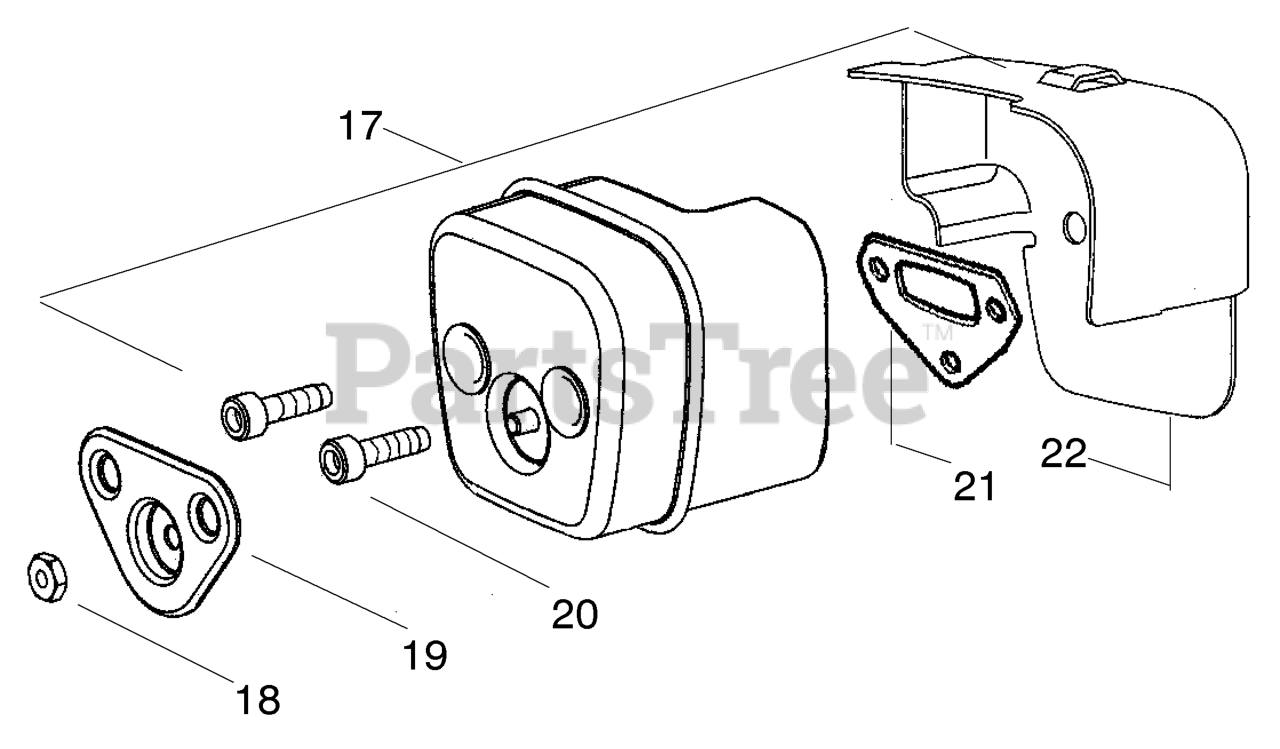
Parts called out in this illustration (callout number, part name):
17	MUFFLER KIT
18	NUT-BRASS
19	COVER BOLT
20	SCREW MUFFLER
21	GASKET-MUFFLER
22	BACKPLATE, MUFFLER
